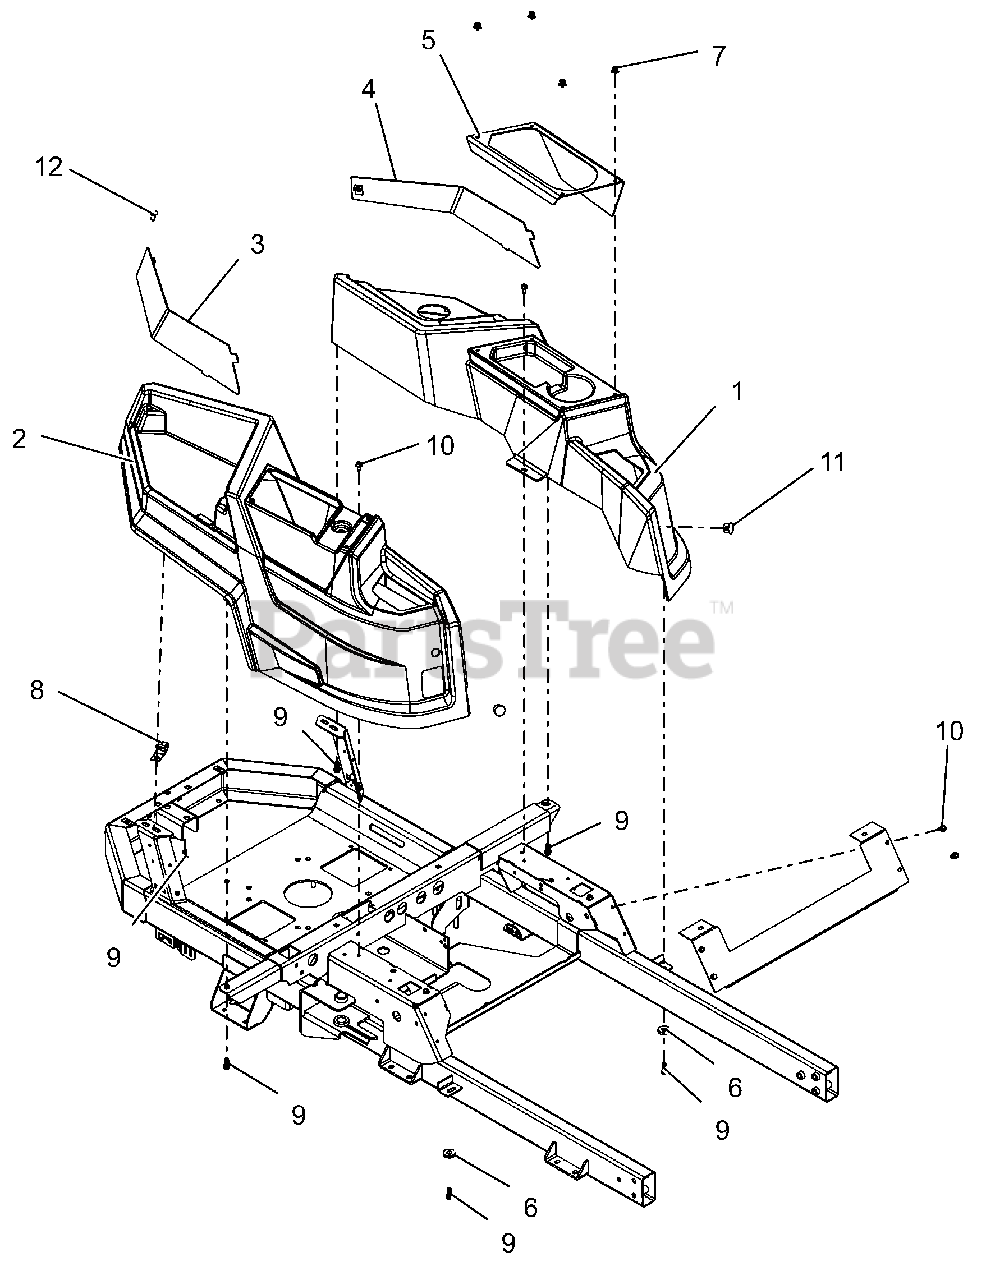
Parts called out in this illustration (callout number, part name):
1	FENDER, LH -ZOOM
2	FENDER, RH -ZOOM
3	WLMT, FENDER BLOCKOFF-RH
4	WLMT, FENDER BLOCKOFF-LH
5	PANEL, CUPHOLDER/STORAGE (LH)
6	WSHR, FLT .406X1.00X.188 ZCC
7	RIVET, PLASTIC .195 DIA.
9	SCR-.312X.75 #14H H/W/H H/L CZ
10	SCR-TAP .25-20X.50 HWH ZCC
11	PLUG, HOLE .75 (BLACK)
12	XMAS TREE FASTNER-BLACK
